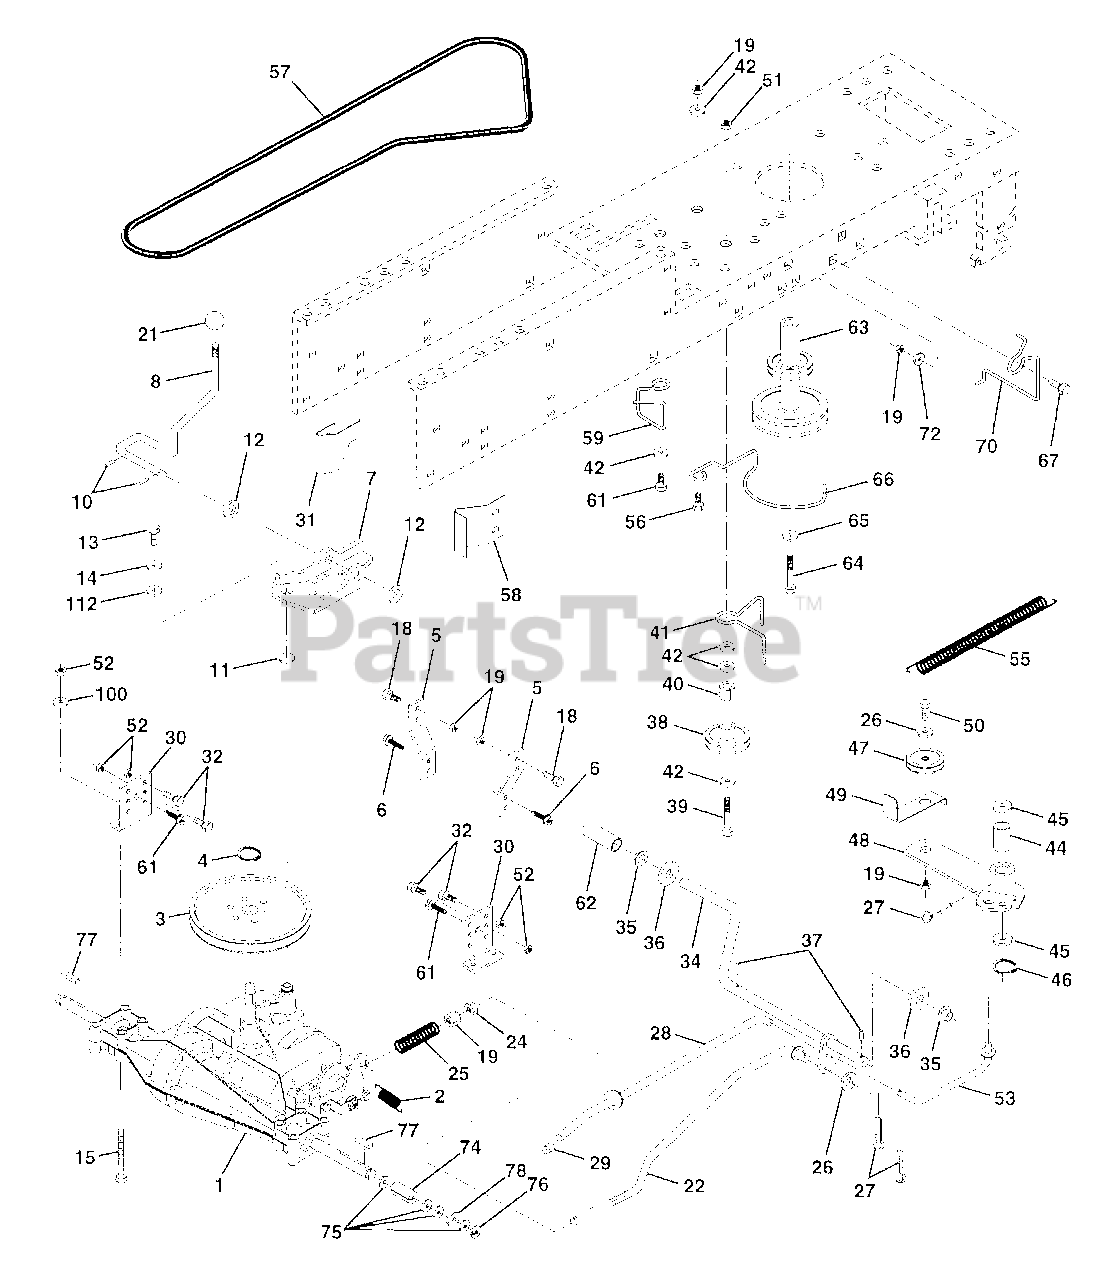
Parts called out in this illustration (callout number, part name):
2	SPRING.BRAKE.RETU
3	PULLEY TRANS
5	STRAP TORQUE
6	SCREW
8	SHIFT ROD
10	PIN COTTER 1/8
11	WASH-SHFT PLT LT
12	WASHER
13	BOLT.1/4-28.W/PAT
14	LOCKWASHER
15	BOLT HEX
18	BOLT
19	NUT
21	KNOB T (1/2-HOLE)
22	BRAKE ROD
24	NUT
25	SPRING ROD LT
27	COTTER PIN
28	ROD.BRAKE.PARK.LT
30	TRANSAXLE MTG BKT
31	"KEEPER,BELT LH T"
32	BOLT
35	NYLON BEARING
36	WASHER LT
38	PULLEY.IDLER.FLAT
39	BOLT
40	SPACER T
41	BELT KEEPER LT
42	WASHER
44	"LY, BEARING"
45	WASHER LT
46	KLIP RING
48	ARM IDLER
49	RETAIN BELT
53	"LINK, CLUTCH T"
55	"SPRING, RETURN LT"
56	WASHER
58	"KEEPER,BELT RH T"
59	KEEPER BELT CNTSP
62	PEDAL COVER T
63	PULLEY.ENGINE
64	BOLT
65	LOCKWASHER
66	KEEPER.BELT.ENG.L
70	KEEPER BELT ENG
72	WASHER
74	SPACER LT
75	WASHER
76	E-RING LT
78	WASHER
100	WASHER M
112	WASHER LT
